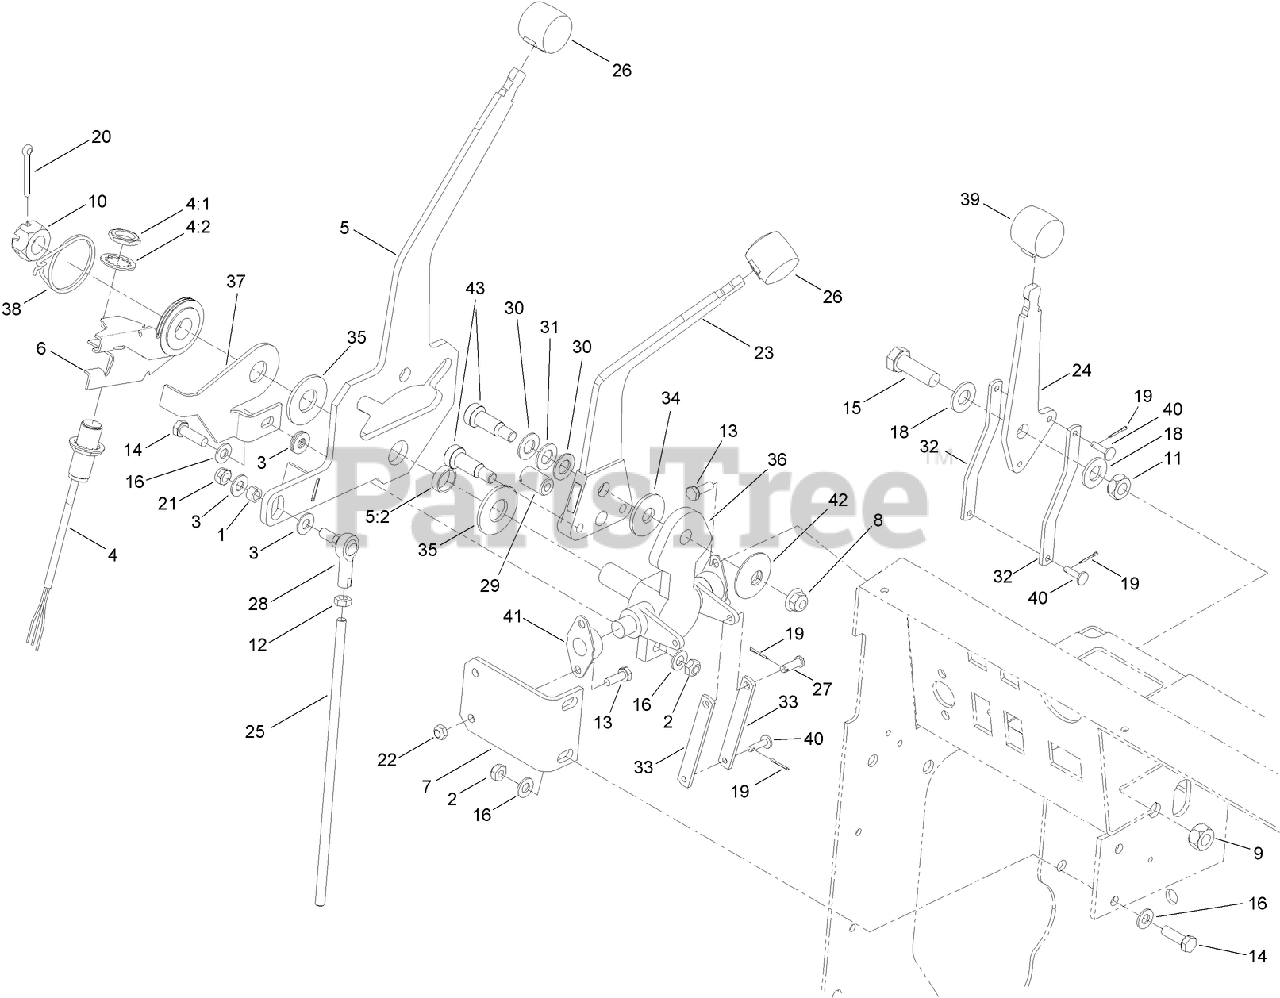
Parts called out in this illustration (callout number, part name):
1	Spacer
2	NUT-HEX
3	WASHER
4	PROXIMITY SWITCH ASM
4:1	NUT-HEX
4:2	WASHER-LOCK, INTERNAL TOOTH
5	HANDLE ASM
5:2	BEARING-HANDLE
6	MOUNTING ASM
7	ANGLE-MOUNTING
8	NUT-HF
9	NUT-LOCK, HEX
10	NUT-SLOTTED, HEX
11	NUT-JAM
12	NUT-JAM
14	SCREW-HH
15	SCREW-HH
16	WASHER-PLAIN
18	WASHER-FLAT
19	PIN-COTTER
20	PIN-COTTER
21	NUT-LOCK, NI
22	NUT-LOCK, CONE
23	HANDLE-CREEP
24	HANDLE-PLOW
25	ROD CONTROL
27	PIN-CLEVIS
28	JOINT-BALL (FEMALE)
29	BALL-PLUNGER
30	RACE-THRUST
31	BEARING-THRUST (NEEDLE)
32	LINK-VALVE, CONTROL
33	LINK-VALVE, STEERING
34	WASHER-FRICTION
35	WASHER-SPACER
36	PIVOT-CONTROL, STEERING
37	PLATE-CENTERING
38	SPRING-CENTERING
39	KNOB-GREEN
40	PIN-CLEVIS
41	BEARING
42	WASHER-BELLEVILLE
43	BOLT-SHOULDER
